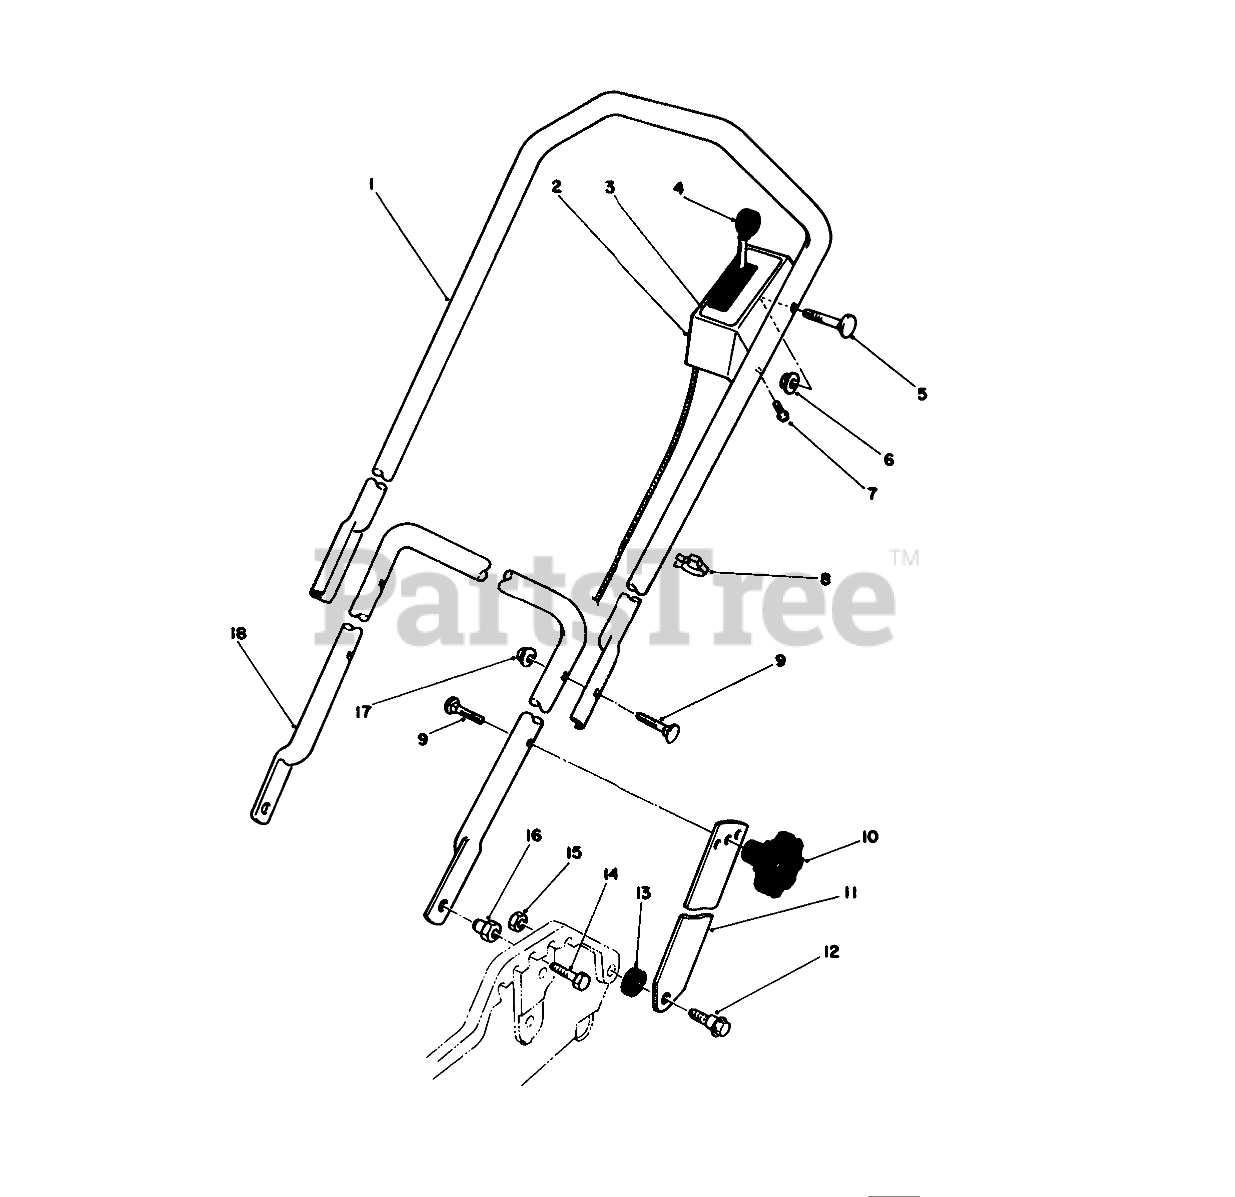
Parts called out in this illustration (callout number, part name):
1	UPPER HANDLE
2	Cover-Control (Incl. Ref. #3)
3	Decal-Control Cover
4	THROTTLE CONT-SERVICE
5	HANDLE SCREW
6	NUT-LOCK, HHF
7	SCREW-HWHTF
9	SCREW
11	Handle Latch
12	SCREW-SHOULDER
13	SPACER
14	SCREW-HH
15	NUT-LOCK, NI
16	HANDLE PIVOT NUT
17	NUT-LOCK, NI
18	LOWER HANDLE
